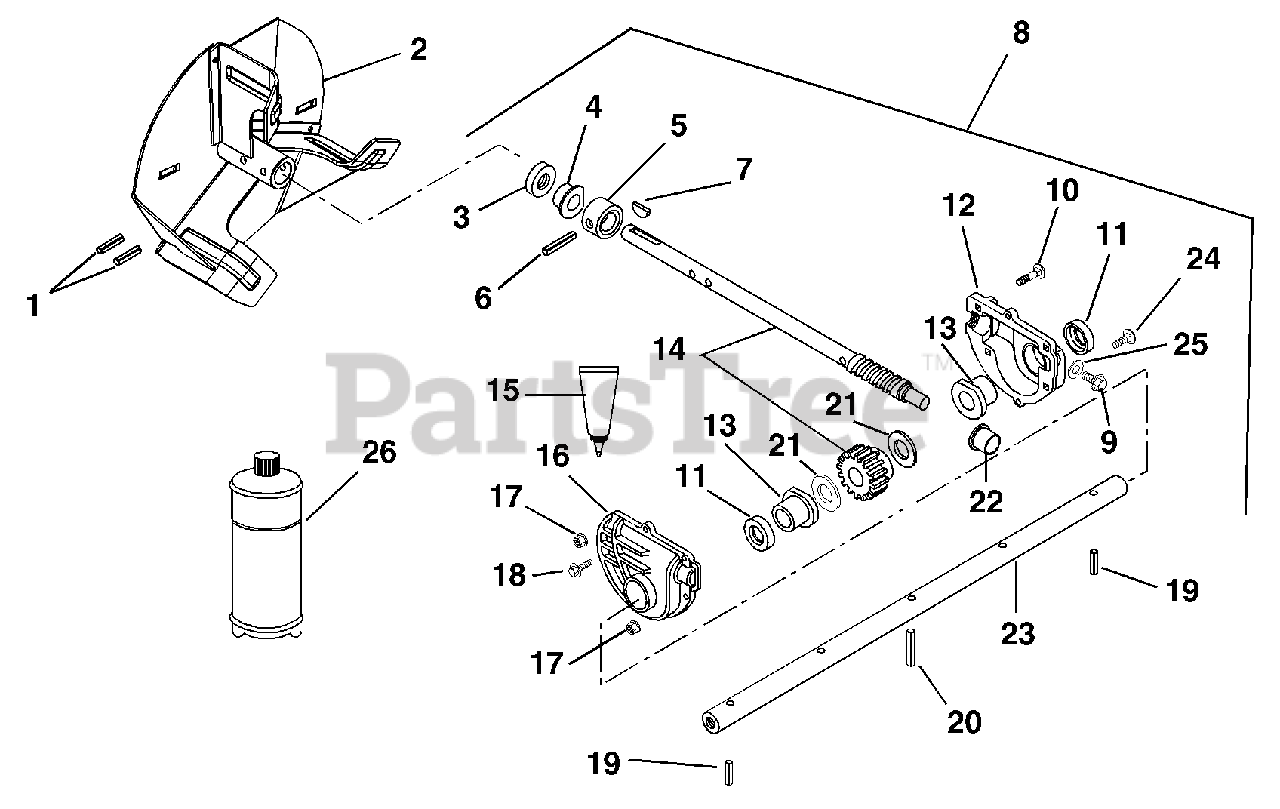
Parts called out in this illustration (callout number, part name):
1	PIN-ROLL .250X1.75
2	IMPELLER - .75 ID X 12" OD
3	SEAL-OIL .750X1.375X.250
4	BSHG-FLG .750X1.000X.750X1.250
5	THRUST COLLAR
6	PIN-GRV .188X1.25 TP A
7	KEY-WDRF .188X.875X.375 SAE11
8	GEAR CASE-LRG BORE-ALUM.- 24"
9	@SCR-TAP .38-16X.50 HWH TR YWZ
10	@BLT-RDHDSQNK .25-20X1.25 G5YZ
11	SEAL-OIL 1.000X1.375X.250
12	CASE, GEAR-LH-LARGE BORE-ALUM.
13	BSHG-FLG 1.00X1.12
14	WORM SHAFT & GEAR ASSY
15	LOCTITE GASKET 518--850CC CRTG
16	CASE, GEAR-RH-LARGE BORE-ALUM.
17	@NUT-SPNLK-FLG .25-20 YWZC
18	SCR-TAP 10-24X.75 HWH TR YWZC
19	PIN-ROLL .188X1.50
20	PIN-GRV .313X1.44 TP C
21	WSHR-HRD-THRS 1.007X1.542X.062
22	BSHG-FLG .502X1X.750
23	SHAFT, RAKE - 24"
24	@BLT-RDHDSQNK .25-20X1.00 G5YZ
25	WSHR-FIBER .437X.656X.032
26	ARIENS 16 OZ.BOTTLE OF L2 LUBE
